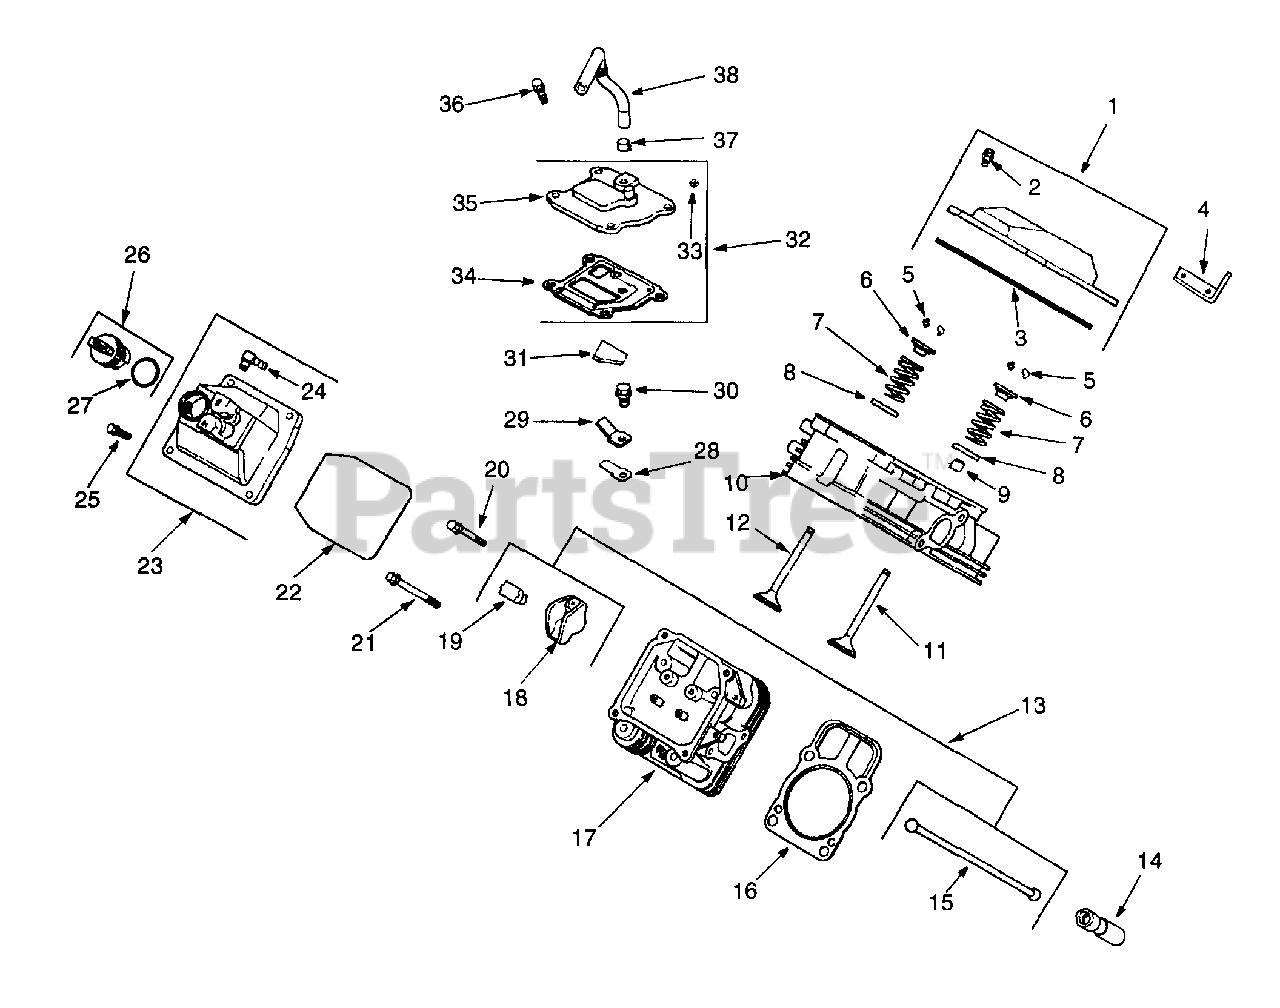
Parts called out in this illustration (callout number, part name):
1	Kit, Valve Cover
2	Screw, Shoulder
3	O-Ring, Valve Cover
4	Strap, Lifting
5	Kit, Retainer
6	Cap, Valve Spring
7	Spring, Valve
8	Retainer, Spring
9	Seal, Valve Stem
10	Head Assembly, #1 Cylinder
11	Valve, Intake (Std.)
12	Valve, Exhaust (Std.)
13	Kit, Valve Train
14	Lifter, Valve
16	Gasket, Cylinder Head
17	Head Assembly, #2 Cylinder
19	Pivot, Rocker Arm
20	Screw, Hex Flange M6 x 1 x 34
21	Screw, Hex Flange M10 x 1.5 x 90
22	O-Ring, Valve Cover
23	Cover, Fuel Pump Valve
24	Connector 90°
25	Screw, Shoulder
26	Cap Assembly, Oil Fill
27	O-Ring
28	Reed, Breather
29	Retainer, Breather Reed
30	Screw, Hex Flange M5 x 0.8 x 10
31	Filter, Breather
32	Kit, Breather
33	Plug, Allen Head 1/8 NPTF
34	Gasket, Breather
35	Cover, Breather
36	Screw, Hex Flange M6 x 1.0 x 20
37	Clamp, Breather
38	Hose, Breather
